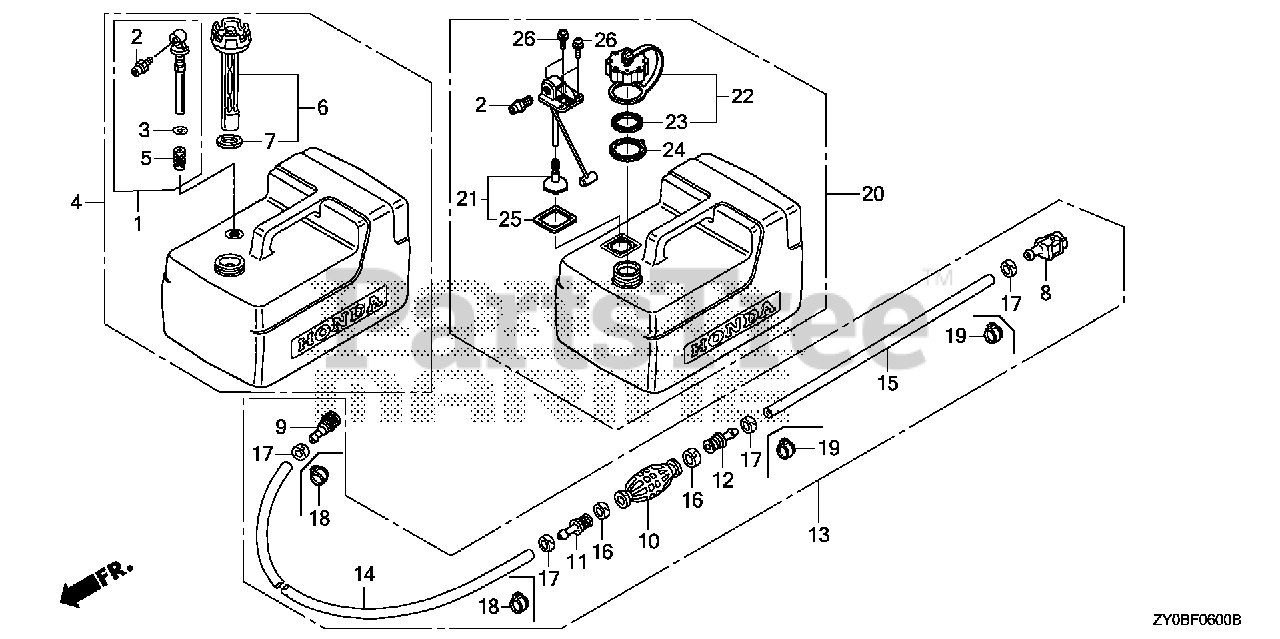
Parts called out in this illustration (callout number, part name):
2	FITTING, QUICK DISCONNECT Use from Frame SN 1205705.
8	CONNECTOR ASSY., FUEL (A)
9	CONNECTOR, FUEL (CONNECTOR TYPE)
10	BULB, PRIMER
11	VALVE, IN.
12	VALVE, OUTLET
13	TUBE ASSY., FUEL TANK
14	TUBE, FUEL LONG (7.3X2000)
15	TUBE, FUEL SHORT
16	BAND, TUBE CLIP (20MM)
18	CLAMP, FUEL TUBE (14.0) (CONNECTOR TYPE)
19	CLAMP, FUEL TUBE (14.0) (CONNECTOR TYPE)
20	TANK ASSY., FUEL
21	FILTER KIT, FUEL
22	CAP, FUEL FILLER
23	GASKET, FUEL CAP
24	RETAINER, PRESSURE RELIEF
25	GASKET, FUEL PICK-UP
26	BOLT-WASHER (5MM) (SEAL)
